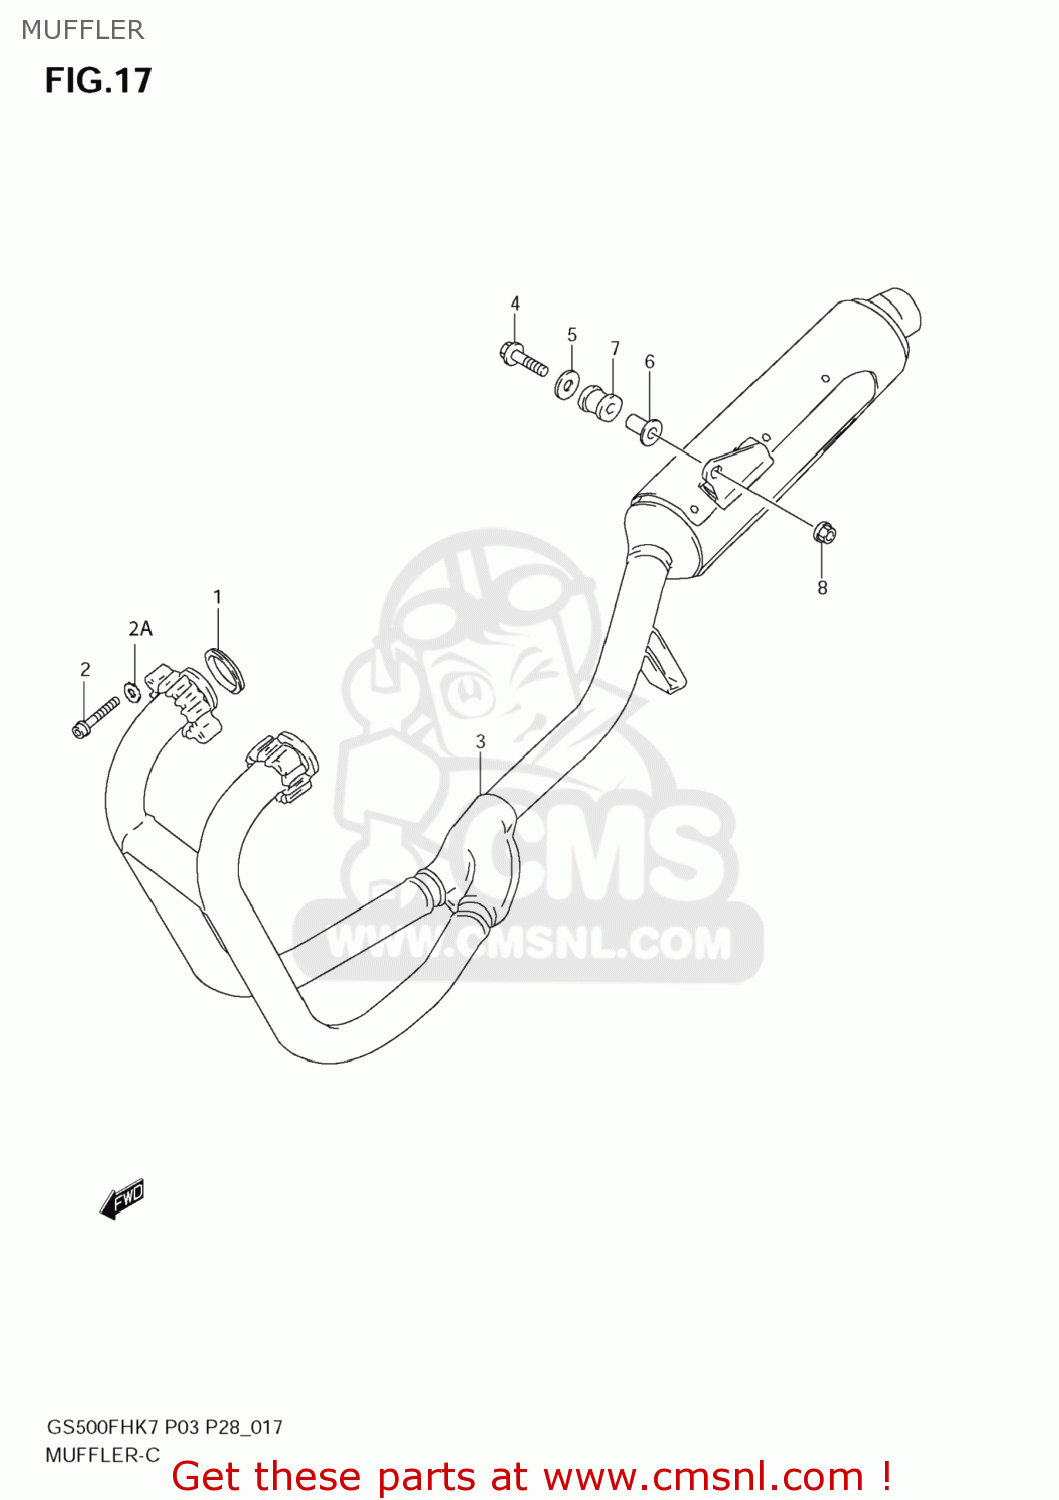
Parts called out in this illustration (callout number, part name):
1	GASKET,EXHAUST PIPE (NAS)
2	BOLT
2A	WASHER
3	MUFFLER
4	BOLT(8X40)
5	WASHER(8.5X28X1.6)
6	SPACER(8.6X12X24.2)
7	CUSHION
8	NUT
